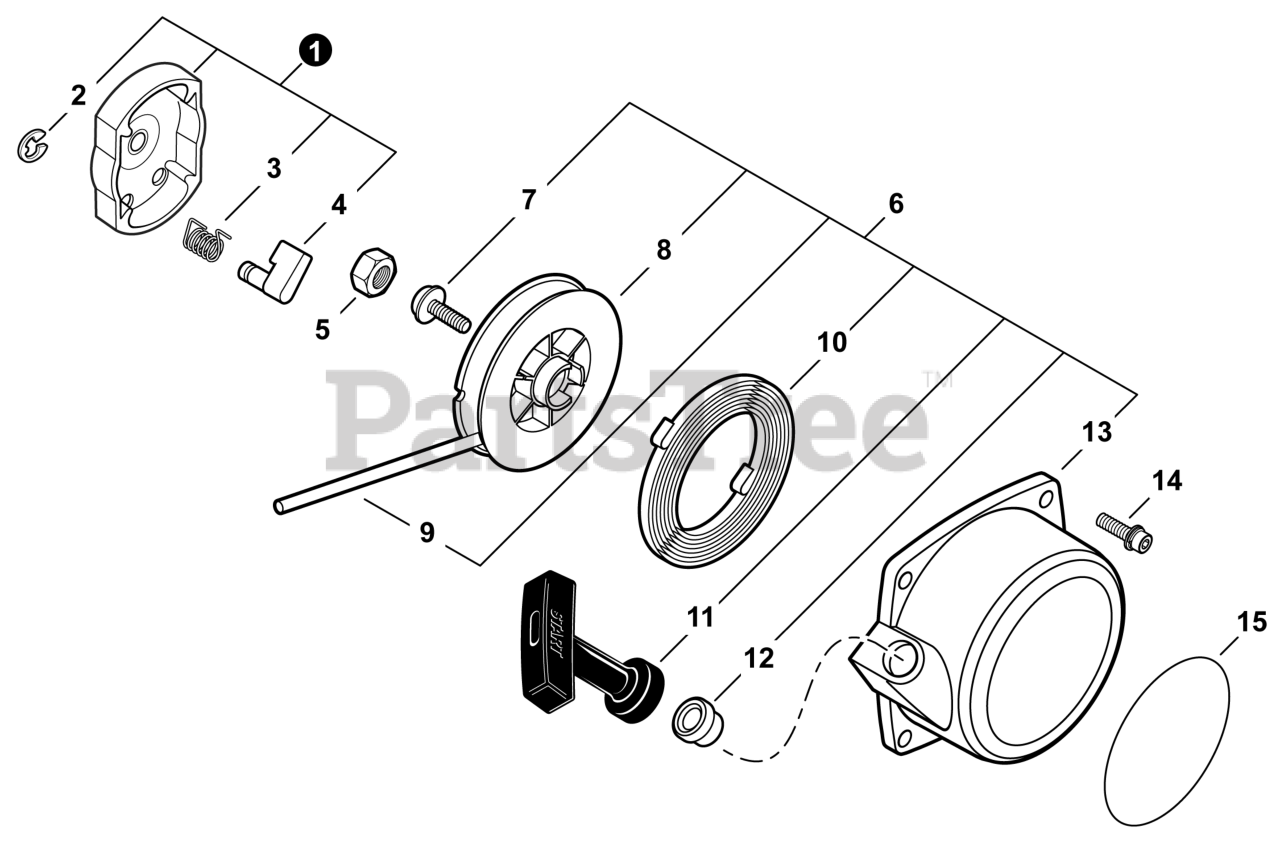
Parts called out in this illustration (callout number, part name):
1	PAWL ASSY, STARTER
2	E-RING 4
3	SPRING, RETURN
4	PAWL, STARTER
5	NUT 8x1.25
6	STARTER ASSY, RECOIL
8	REEL, ROPE
9	ROPE, STARTER 3.8x1150
10	SPRING, RECOIL
11	GRIP, STARTER
12	GUIDE, ROPE
13	CASE, STARTER
14	BOLT 5x20
15	LABEL - RECOIL STARTER
